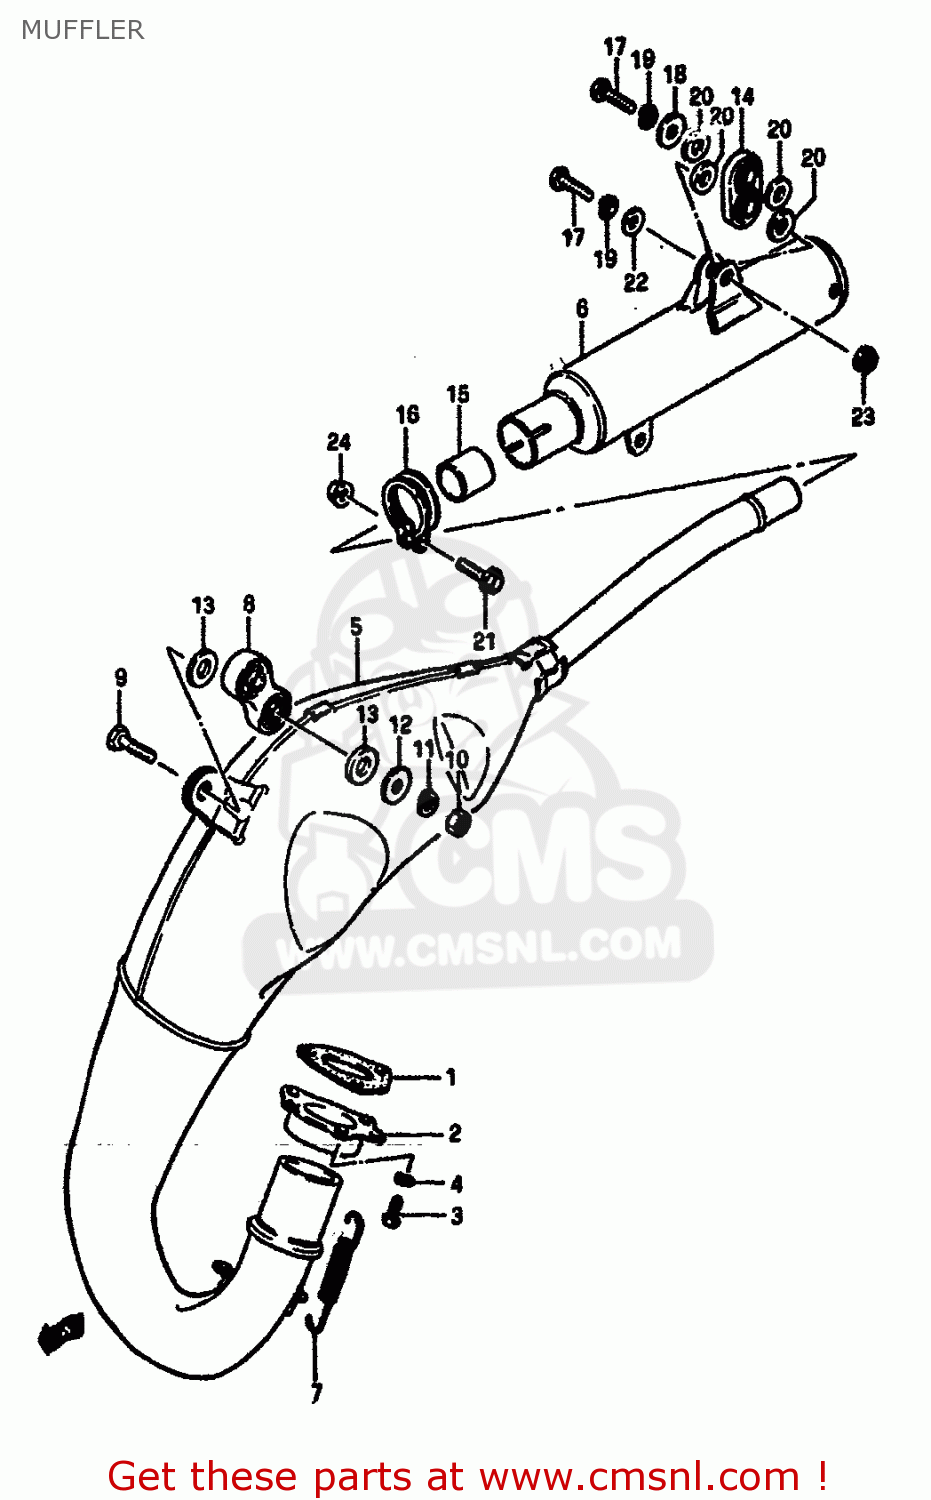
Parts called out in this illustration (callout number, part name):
1	GASKET,EXHAUST PIPE (MCA)
2	FLANGE,EXHAUST PIPE
3	SCREW
4	LOCK WASHER
5	MUFFLER,1ST
6	MUFFLER,2ND
7	SPRING
8	DAMPER,MUFFLER
9	BOLT(8X32)
10	NUT 8MM
11	LOCK WASHER
12	WASHER
13	WASHER(13X28X1.6)
14	DAMPER,MUFFLER,SECOND
15	GASKET,SECOND MUFFLER (NAS)
16	CLAMP,MUFFLER SECOND
17	BOLT
18	WASHER
19	LOCK WASHER
20	WASHER(10.5X20X2.5)
21	BOLT
22	WASHER
23	NUT
24	NUT 6MM
